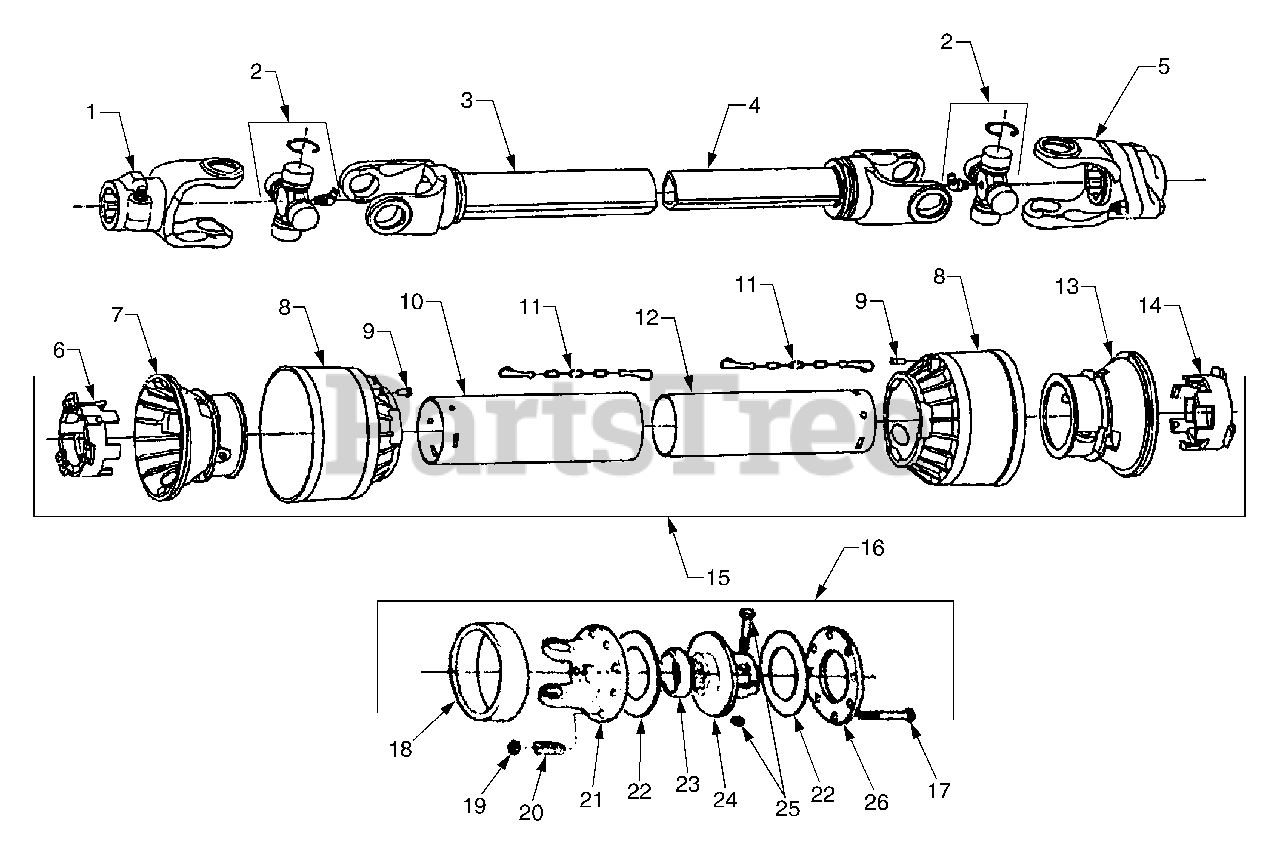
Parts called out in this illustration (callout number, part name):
1	Yoke 1 3/8 6
2	Cross, Bearing
3	Outer Tube & Yoke
4	Inner Tube & Yoke
5	Yoke, Shearbolt
6	Tube Bearing Outer
7	Outer Tube Rigid Cone
9	Pin For Stop Rotation
10	Outer Shield
12	Inner Shield
13	Inner Tube Rigid Cone
14	Tube Bearing Inner
15	Shield Complete
16	Slip Clutch Yoke Complete
17	Bolt M10x80
18	Dirt Shield
19	Nut 10MM Nylock
21	Yoke Slip Clutch
22	Friction Disk
24	Body Friction Clutch
25	Bolt M12x65 With Nut
26	Outer Flange
